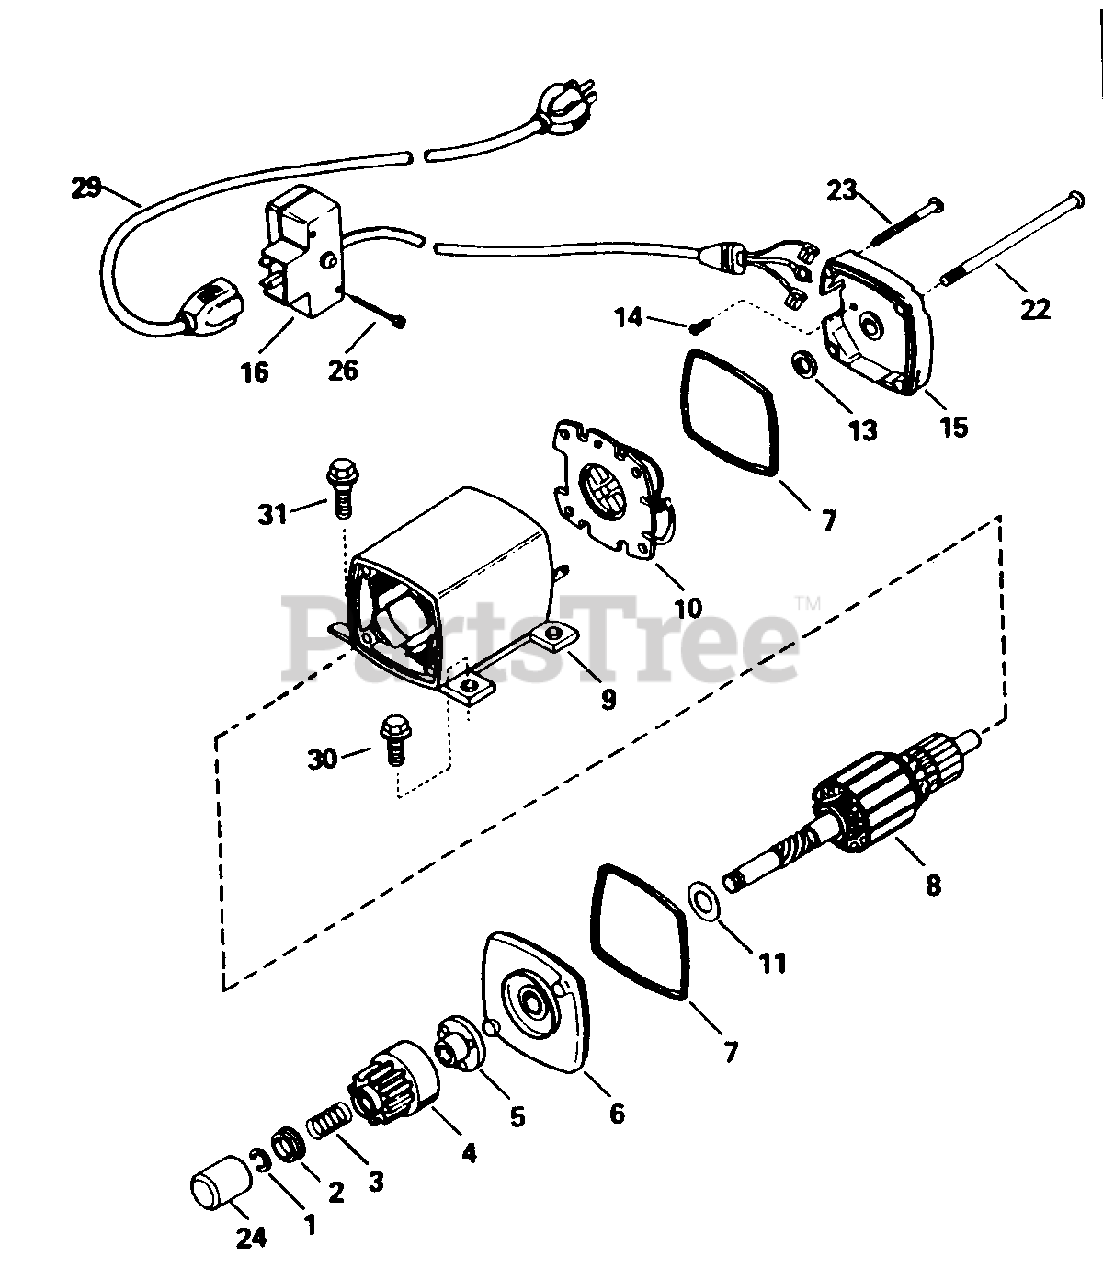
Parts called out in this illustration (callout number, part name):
1	Ring, Retainer
2	Retainer, Spring
3	Spring, Anti-drift
5	Nut and Retainer
6	Cap Ass'y., Drive End
9	Housing Ass'y.
10	Card Ass'y., Brush
11	Washer, Thrust
13	Washer, Thrust
14	Screw, Ground
15	Cap Ass'y., Commutator End
16	Box Ass'y., Switch
22	Bolt, Case
23	Screw, Grounding
24	Cover, Dust
26	Screw, Hex Hd. Self-Tap, 6-32 x 2-1/2
29	Cord, Extension (10' 6")
30	Screw, Fil. Hd. Sems, 1/4-20 x 9/16
31	Screw, Hex Hd. Shoulder, 1/4-20 x 1/2
